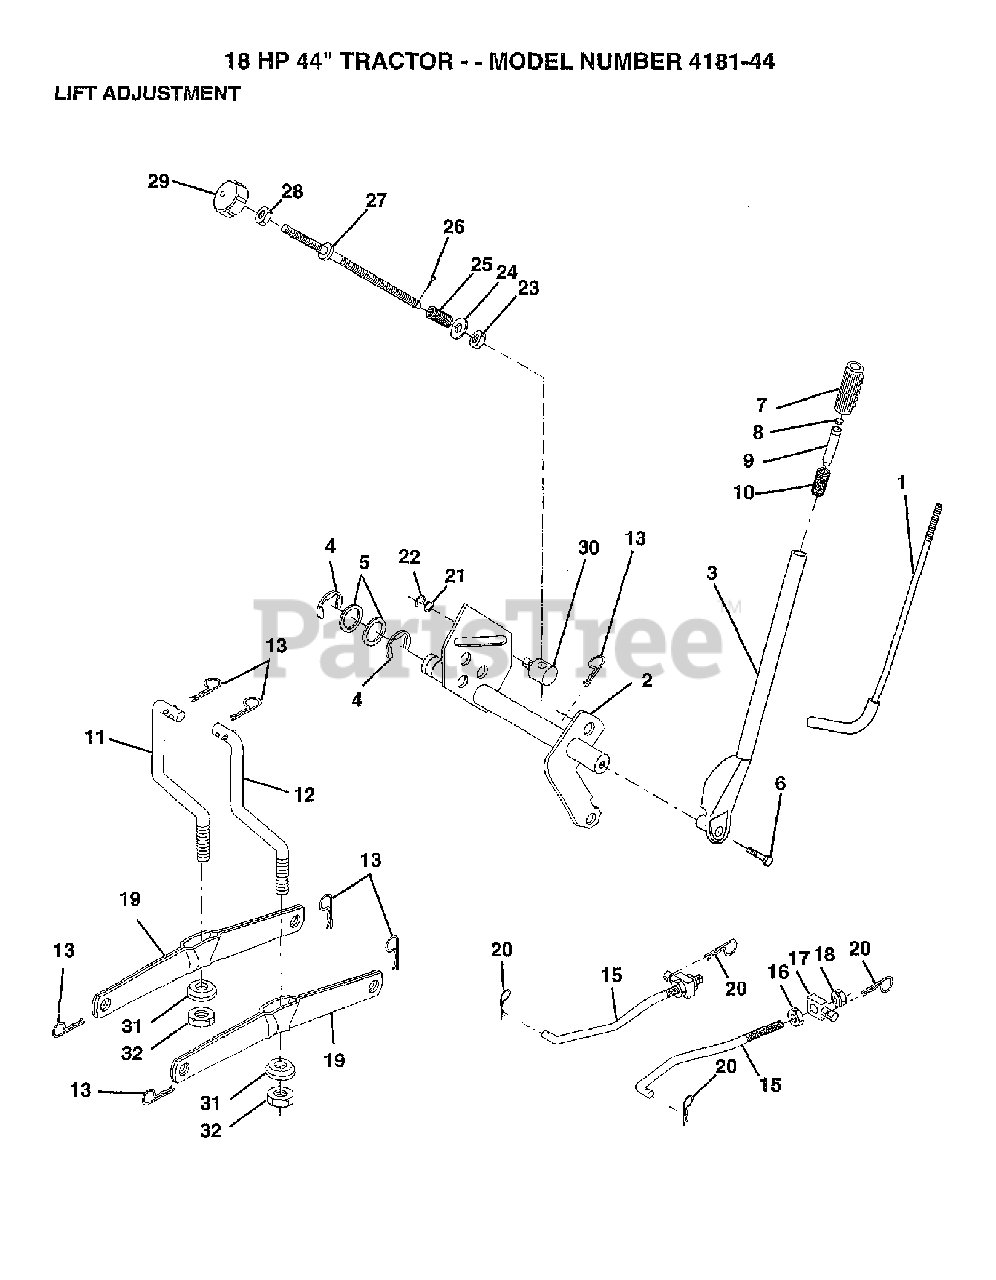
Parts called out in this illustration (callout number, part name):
1	LEVER ROD LT
3	LIFT LEVER KIT
6	Hex Bolt
7	GRIP
8	PLUNGER BUT KIT
9	PLUNGER BUT KIT
11	LINK LIFT LH
12	Lift Link Assembly, RH
13	RETAINER SPRING
15	FRONT LINK
16	NUT.HEX.JAM.1/2-13
18	NUT.LK.W/WSH.1/2.
19	ARM.REAR.SUSPENSION
20	SPRING RETAINER
21	WASHER
22	KLIP RING
24	WASHER
27	ROD LIFT LT
28	NUT
29	KNOB INF 3/8-16
30	TRUNION LT
32	NUT CROWNLOCK 3/8-24
